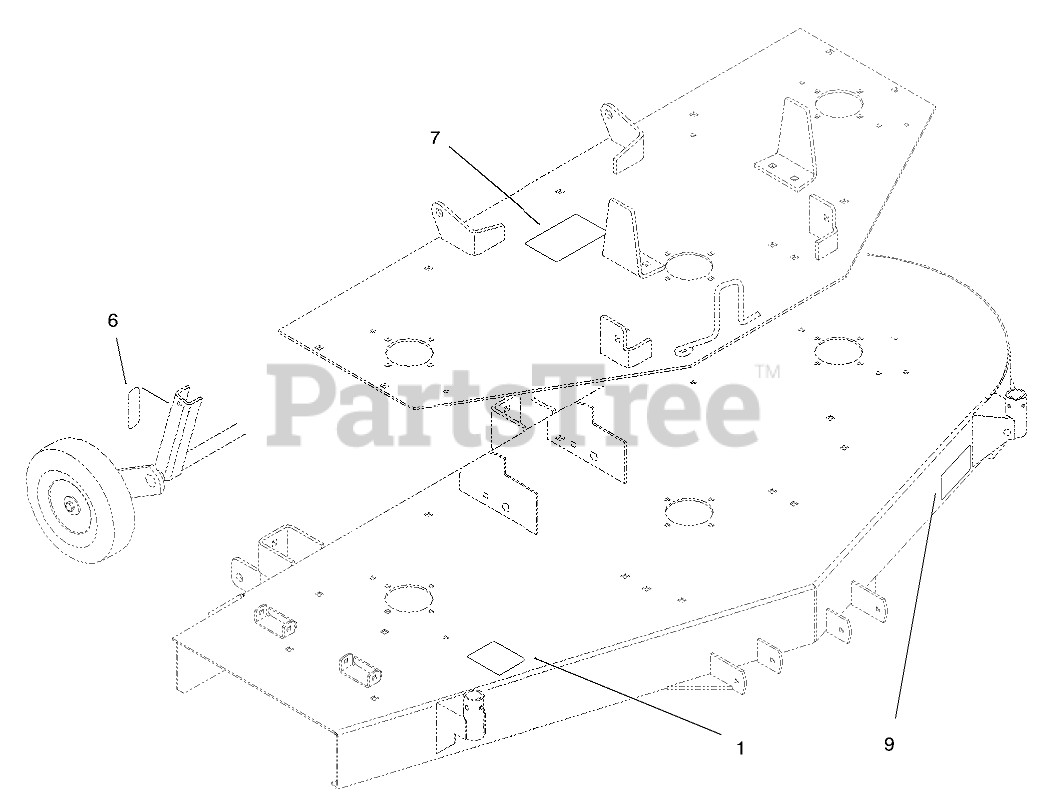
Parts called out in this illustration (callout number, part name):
1	DECAL-BELT ROUTING
6	Decal-Height Of Cut (Only On: 78395)
7	DECAL-BELT ROUTING
9	DECAL-ADJUSTMENT, WHEEL
